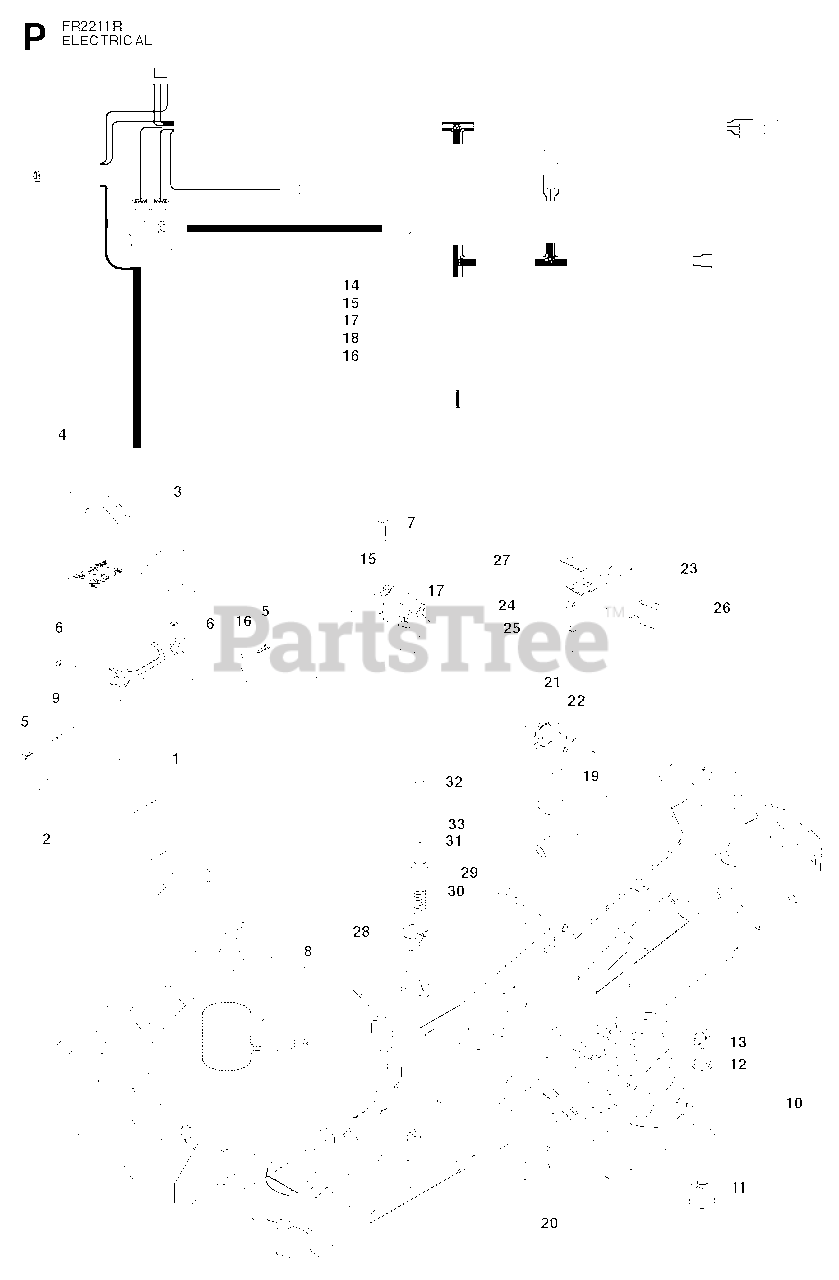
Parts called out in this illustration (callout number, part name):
5	SCREW EHHM
10	IGNITION SWITCH
11	IGNITION SWITCH
12	NUT
13	IGNITION KEY
21	%BRAKER
26	SPRING
31	SPACER TUBE
32	SCREW
33	WASHER BRB 8.4X17
